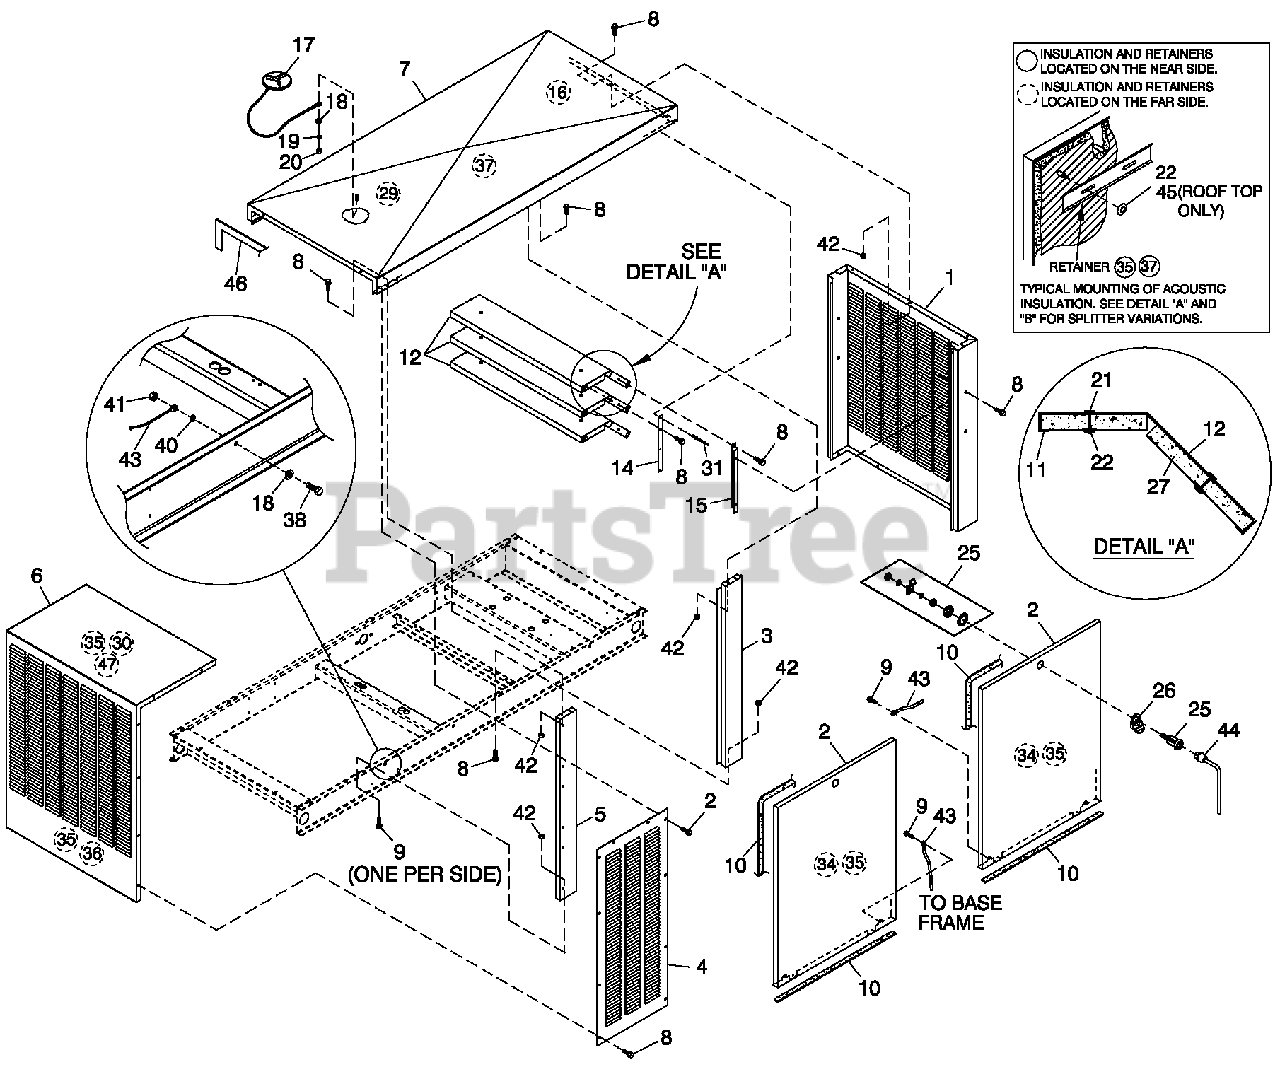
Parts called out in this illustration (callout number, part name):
1	REAR WRAP C3
2	DOOR C3
3	CENTER SUPPORT C3
4	DISCHARGE DUCT LH & RH SIDE C3
5	FRONT CORNERS C3
6	DISCHARGE CENTER DUCT C3
7	ROOF C3 ALUM
8	SCREW THF M6-1 X 16 N WA ZIJS
9	SCREW TH-FRM M6 WICAP SHKPRF W
10	GASKET EXTRUDED TRIM (547" LG)
11	INSULATION SPLITTER SML
12	SPLITTER
14	STRINGER SPLITTER C3
15	SUPPORT SPLITTER C5 130KW
16	INSULATION ROOF TOP REAR
17	ASSEMBLY COVER ACCESS
18	WASHER FLAT 1I4-M6 ZINC
19	WASHER LOCK M6-1I4
20	NUT HEX 1I4-20 STEEL
21	INSULATION RETAINMENT HANGER
22	WASHER SELF LOCKING DOME #4-40
25	VISE-ACTION LATCH SLOTTED CIR
26	TAB PULL
27	INSULATION SPLITTER
29	INSULATION ROOF TOP
30	INSULATION DUCT TOP
31	RIVET POP,1875 X ,450 SS
32	SPLITTER EXTENDED LENGTH
33	INSULATION SPLITTER EXTENDED LENGTH
34	INSULATION DOOR
35	RETAINER INSULATION (820)
36	INSULATION DUCT FRONT
37	RETAINER INSULATION (740)
38	SCREW HHC M6-1,0X 20 G8,8
40	WASHER SHAKEPROOF INT 1I4
41	NUT HEX M6X 1,0 G8YEL CHR
42	NUT HEX LOCK M6-1,0 SS NY INS
43	ASSY WIRE 14 AWG 34,8" GRNIYEL
44	KEY VISE-ACTION LATCH SLOT CIR
45	WASHER SELF LOCKING DOME #8-32
46	STRIP SEALANT 1I8 X 1 (44,52" LG)
47	REFLECTIVE HEAT SHIELD 2,4L
